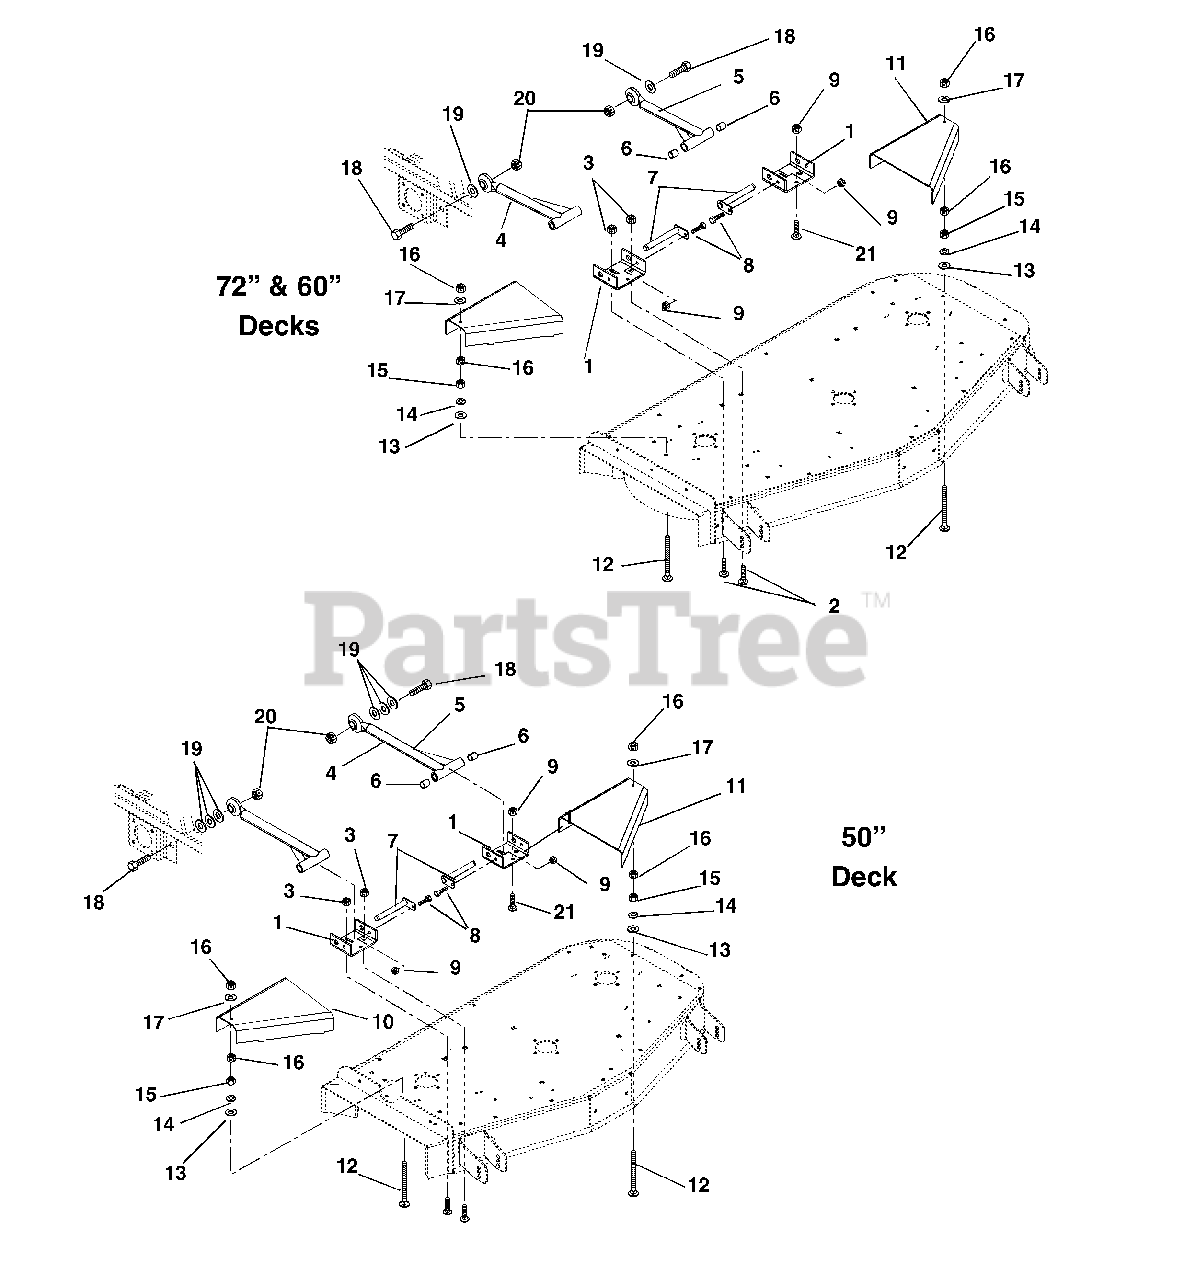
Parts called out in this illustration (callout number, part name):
1	Bracket, Mower Mounting (Rear)
2	Bolt-Round Head Square Neck .50-13 x 1.00 Grade 2
3	Nut-Locking-Center .50-13
4	Assembly, Mower Mounting Arm
5	Weldment-Mower Mounting Arm
6	Bearing .75 x .875 x 1.00
7	Weldment, Mower Mounting Pin
8	Bolt-Hex .38-16 x .75 Grade 5
9	Nut-Locking-Center .38-16
10	Guard, Pulley Right Hand (60" Deck)
10	Guard, Pulley Right Hand (50" Deck)
10	Guard, Pulley Right Hand (72" Deck)
11	Guard, Pulley Left Hand (60" Deck)
11	Guard, Pulley Left Hand (50" Deck)
11	Guard, Pulley Left Hand (72" Deck)
12	Bolt-Round Head Square Neck .31-18 x 3.50
13	Washer-Flat-Steel .344 x .688 x .065
14	Washer-Locking .31 x .078
15	Nut-Hex .31-18
16	Nut-Locking-Center .31-18
17	Washer-Flat-Steel .438 x 1.00 x.083
18	Bolt-Hex .875-9 x 2.75 Grade 5
19	Washer-Flat-Steel .875 x 1.50 x .120 (60" & 72" Deck)
19	Washer-Flat-Steel .875 x 1.50 x .120 (50" Deck)
20	Nut-Locking-Center .875-9
21	Bolt-Round Head Square Neck .38-16 x 1.00 Grade 5 (60" & 72" Deck)
21	Bolt-Round Head Square Neck .38-16 x 1.00 Grade 5 (50" Deck)
